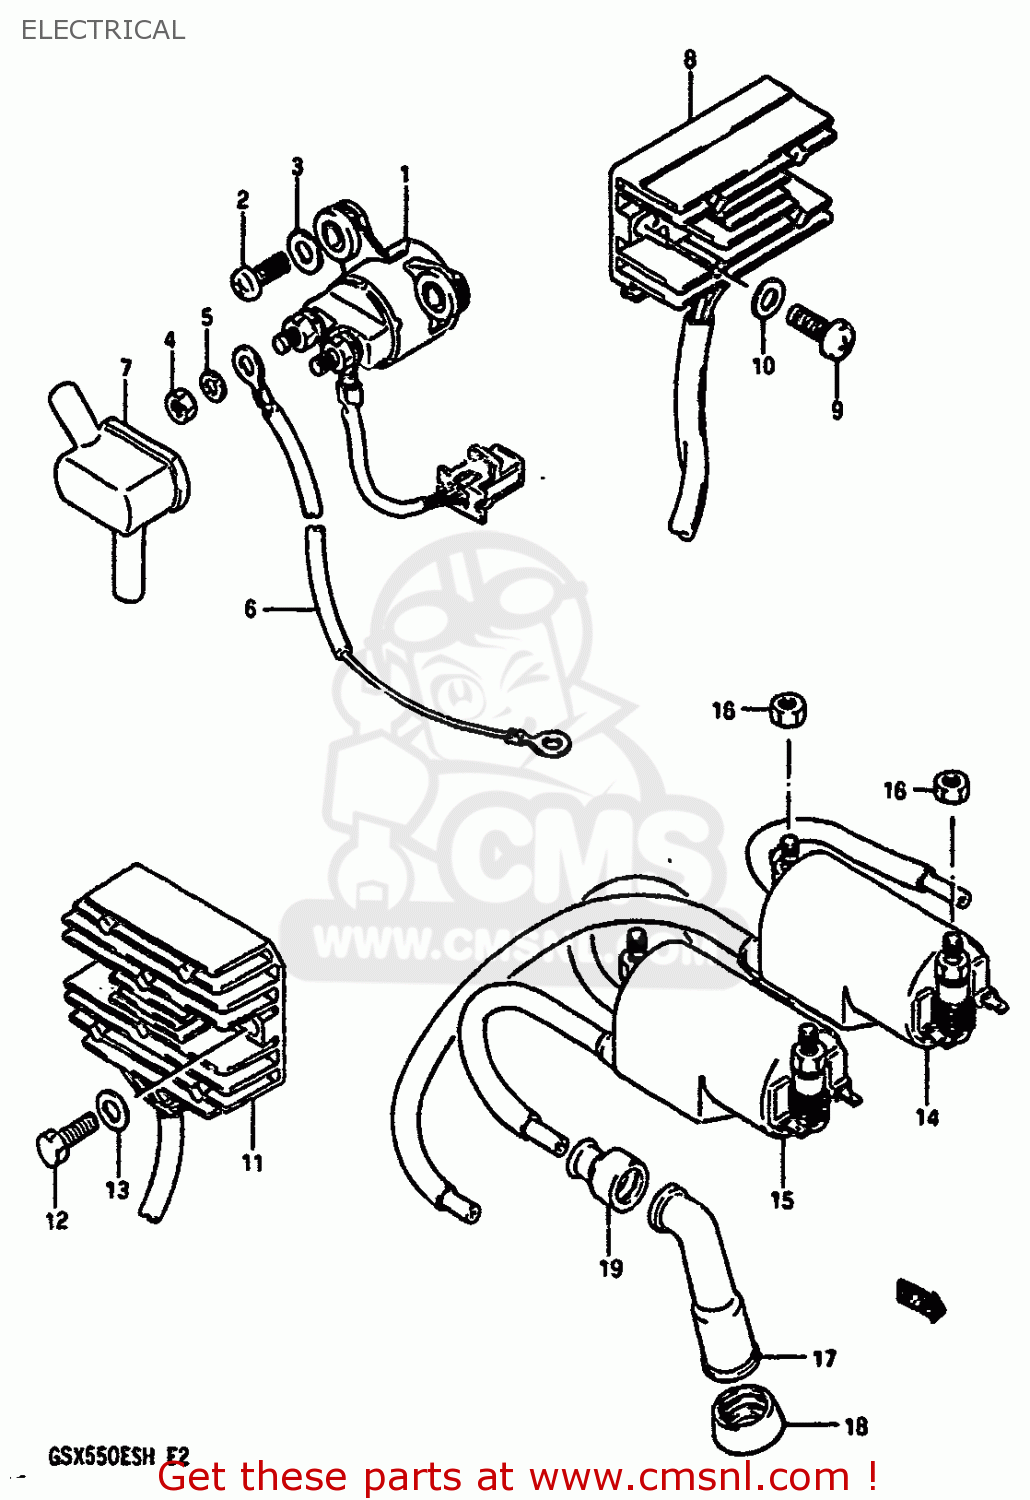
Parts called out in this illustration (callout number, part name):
1	RELAY ASSY,STARTING MOTOR
2	SCREW
3	WASHER
4	NUT
5	WASHER,LOCK
6	WIRE,STARTER MOTOR LEAD
7	CAP,STARTER RELAY TERMINAL
8	RECTIFIER ASSEMBLY
9	SCREW
10	WASHER, LOWER
11	RECTIFIER ASSEMBLY
12	SCREW(6X20)
13	WASHER
14	COIL ASSEMBLY,IGNITION
15	COIL ASSEMBLY,IGNITION
16	NUT
17	CAP ASSY,SPARK PLUG
18	SEAL,SPARK PLUG CAP
19	SEAL,SPARK PLU
